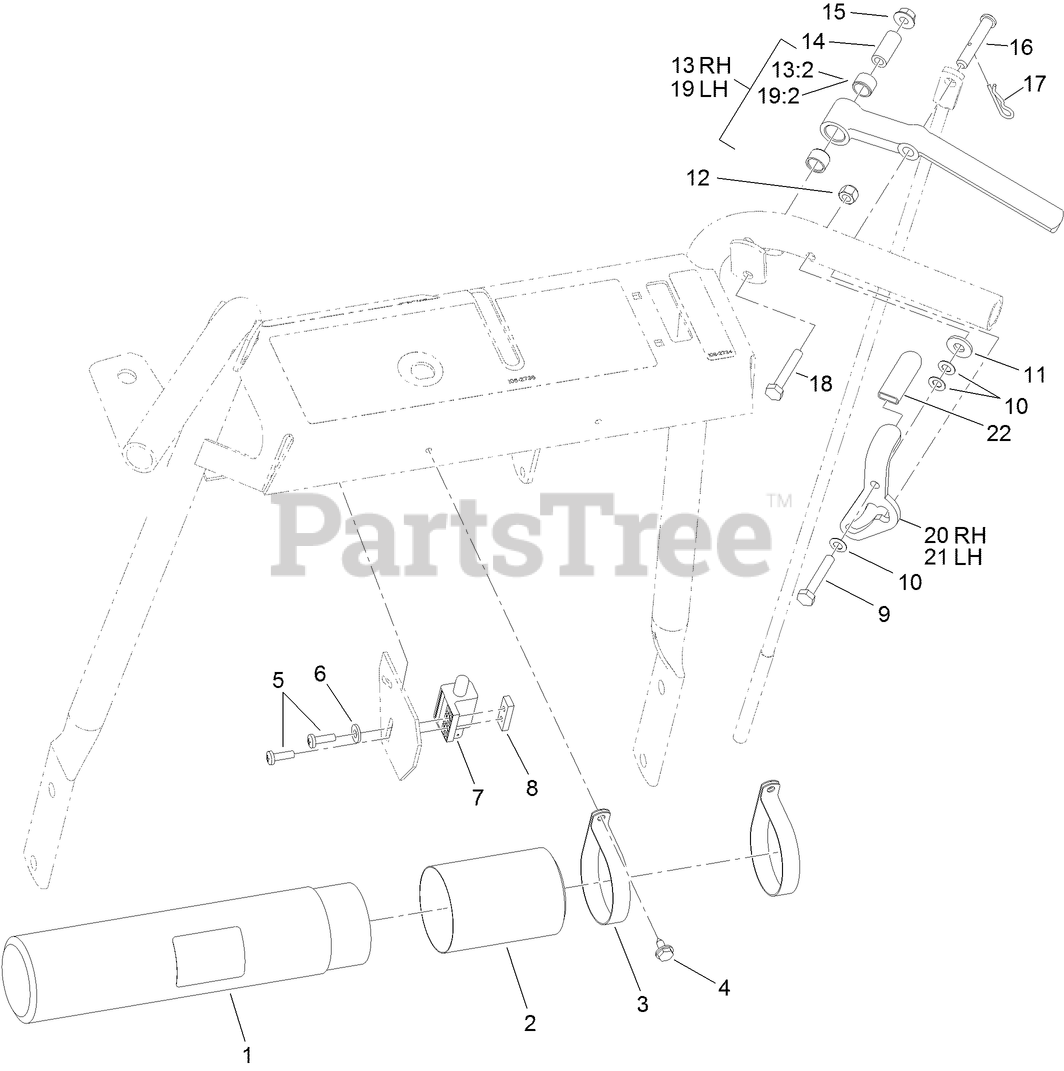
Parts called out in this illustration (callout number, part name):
1	TUBE-MANUAL
2	CAP-HOUSING
3	CLAMP-R
4	SCREW-HWHTF
5	SCREW-PPH
6	WASHER-FLAT
7	SWITCH-OPEN, NORMALLY
8	PLATE-TAPPED
9	SCREW-HH
10	WASHER-SPRING
11	WASHER-FLAT
12	NUT-LOCK, NI
13	RH Drive Lever ASM
13:2	BUSHING-SLEEVE
14	Bushing-Lever, Drive
15	NUT-HF
16	Pin-Clevis
17	PIN-COTTER
18	SCREW-HH
19	LH Drive Lever ASM
19:2	BUSHING-SLEEVE
20	RH LATCH and GRIP ASM
21	LH LATCH GRIP ASM
22	GRIP-LATCH
